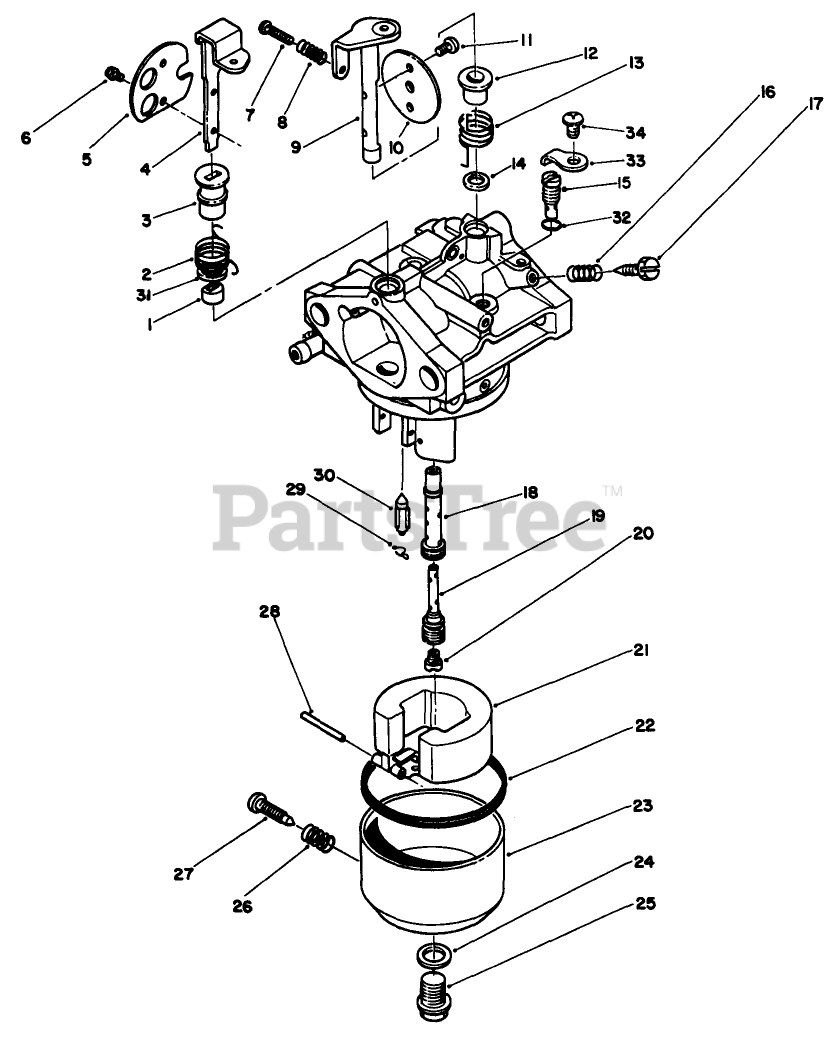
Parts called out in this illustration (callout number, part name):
4	Shaft-Choke
5	Valve-Choke
9	Shaft-Throttle
10	Valve-Throttle
19	Pipe-Bleed
23	Chamber-Float (Incl. Ref. #26 27)
30	Valve-Float
